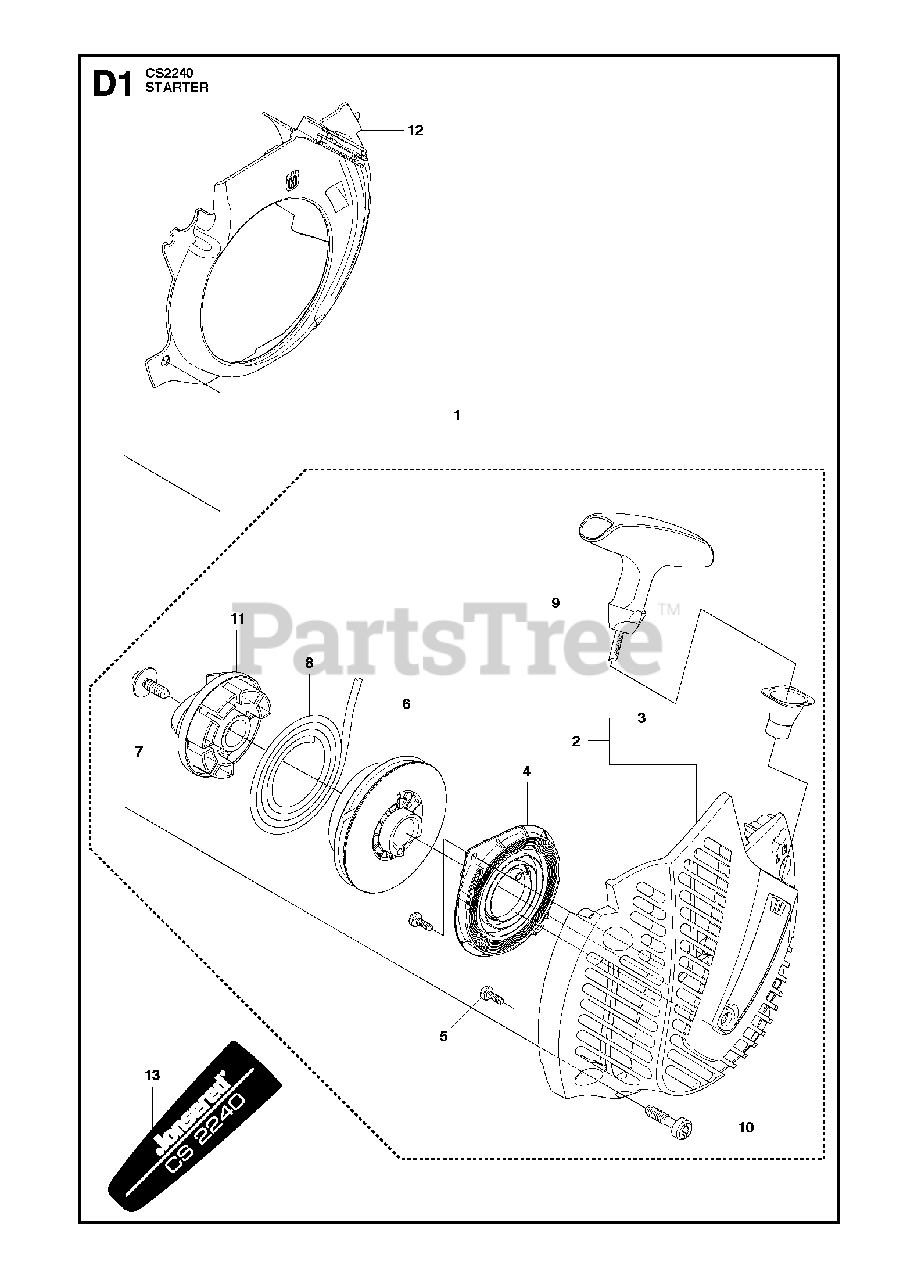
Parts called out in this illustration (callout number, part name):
2	STARTER HOUSING
3	SLEEVE
4	SPRING CASSETTE ASSY
5	SCREW
6	STARTER PULLEY
7	SCREW
8	STARTER ROPE
9	STARTER HANDLE
10	SCREW
12	COOLING AIR CONDUCTOR
